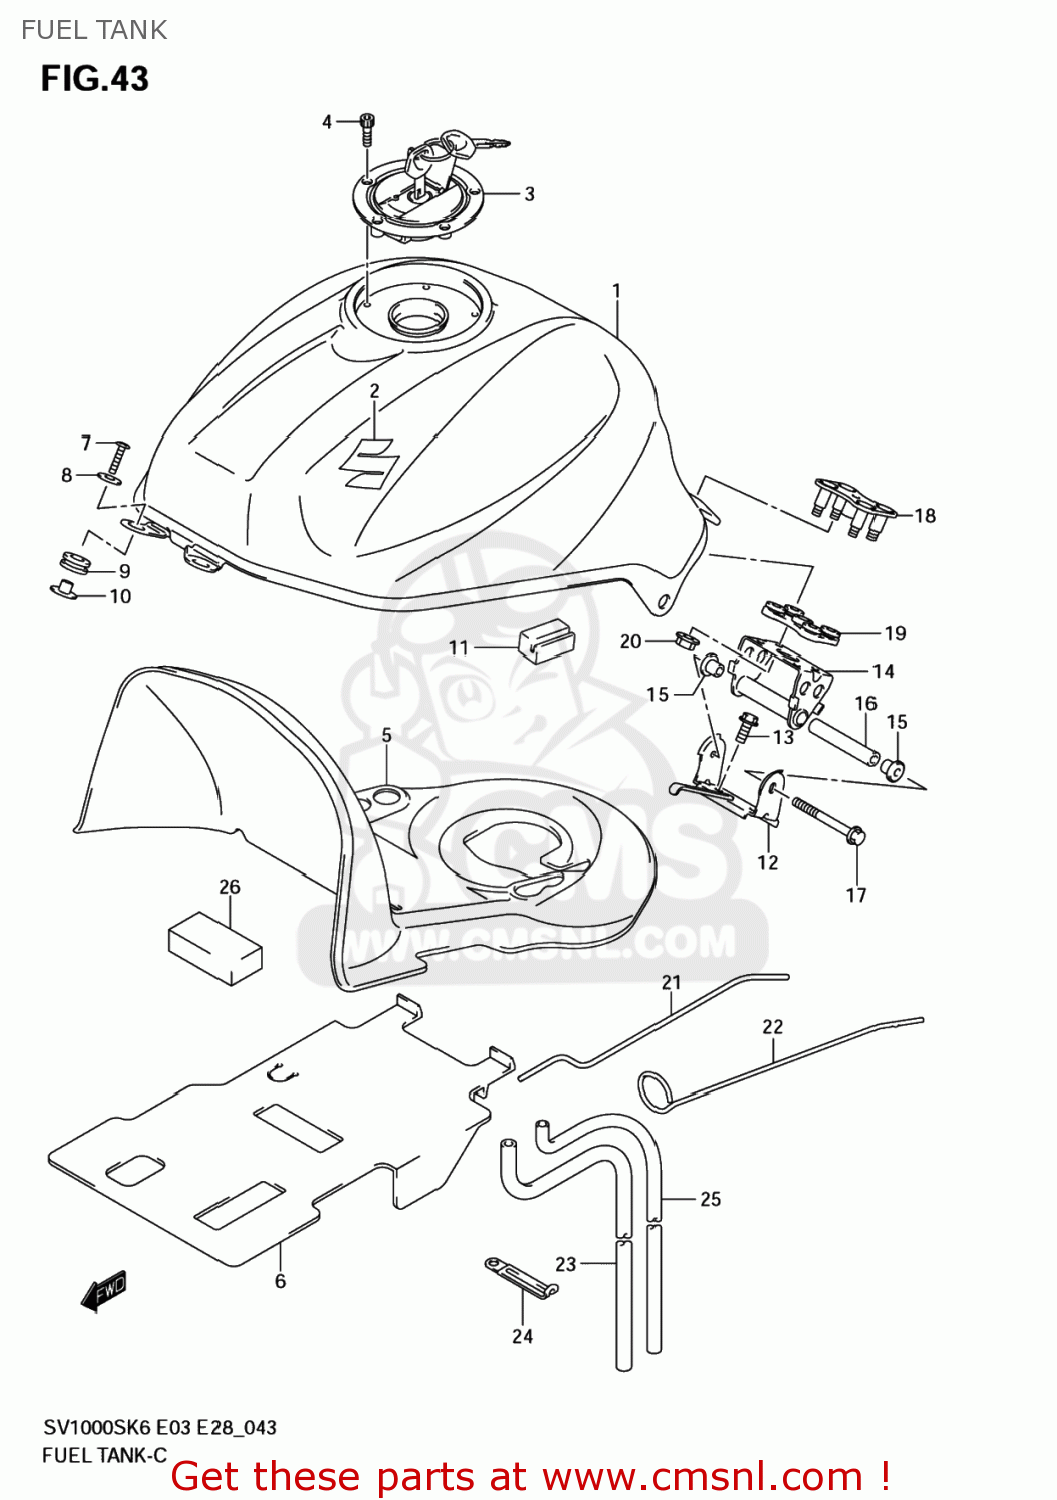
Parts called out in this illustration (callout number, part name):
1	TANK ASSY, FUEL (BLUE)
2	EMBLEM,S
3	CAP SET,FUEL TANK
4	BOLT(5X20)
5	SHIELD,FUEL TANK HEAT
6	SHEET,HEAT SHIELD RUBBER
7	SCREW(6X25)
8	WASHER(6.5X22X1.6)
9	CUSHION,FUEL TANK FR
10	SPACER,FUEL TANK FR
11	CUSHION,FUEL TANK SIDE
12	BRACKET,FUEL T
13	BOLT
14	BRACKET,FUEL TANK NO.1
15	CUSHION,TANK RR BRACKET
16	SPACER,FUEL TANK RR
17	BOLT(6X100)
18	BRACKET,FUEL TANK RR UP
19	CUSHION,FUEL TANK RR
20	NUT
21	STAY,FUEL TANK
22	HOSE,WATER DRAIN
23	CLAMP(L:80)
24	HOSE,FUEL TANK
25	CUSHION,FUEL TANK
26	MOLDING
